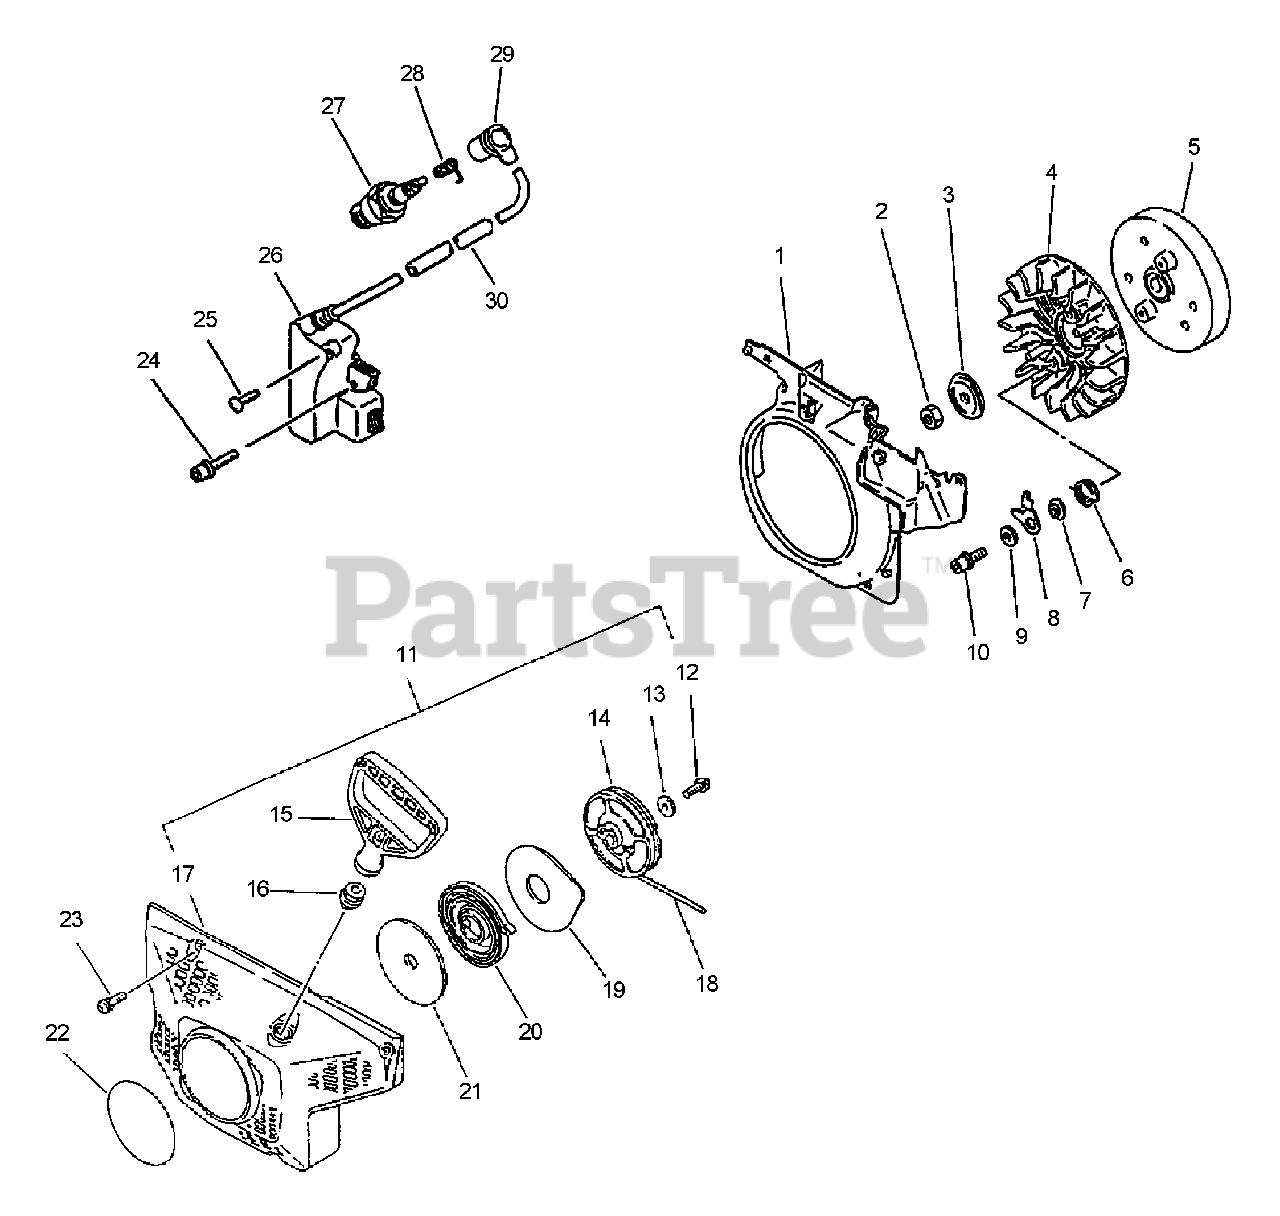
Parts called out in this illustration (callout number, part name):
1	SHIELD, FAN
3	WASHER - CUP
5	FLYWHEEL
6	SPRING, RETURN
8	PAWL, STARTER
9	WASHER - 5
10	SCREW - 5X20
11	STARTER ASSY
12	SCREW - 5X14
13	WASHER - 5
14	REEL, ROPE
15	GRIP, STARTER
16	GUIDE, ROPE
17	CASE, STARTER
18	ROPE, STARTER - 4X900
19	PLATE, STARTER
20	SPRING, REWIND
21	PLATE, STARTER
22	LABEL - ECHO
23	SCREW - 5X14
24	SCREW - 4X20
25	SCREW - 4X8
26	COIL, IGNITION
27	SPARK PLUG -- CJ-6Y
28	TERMINAL, SPARK PLUG CAP
29	CAP, SPARK PLUG
30	TUBE
